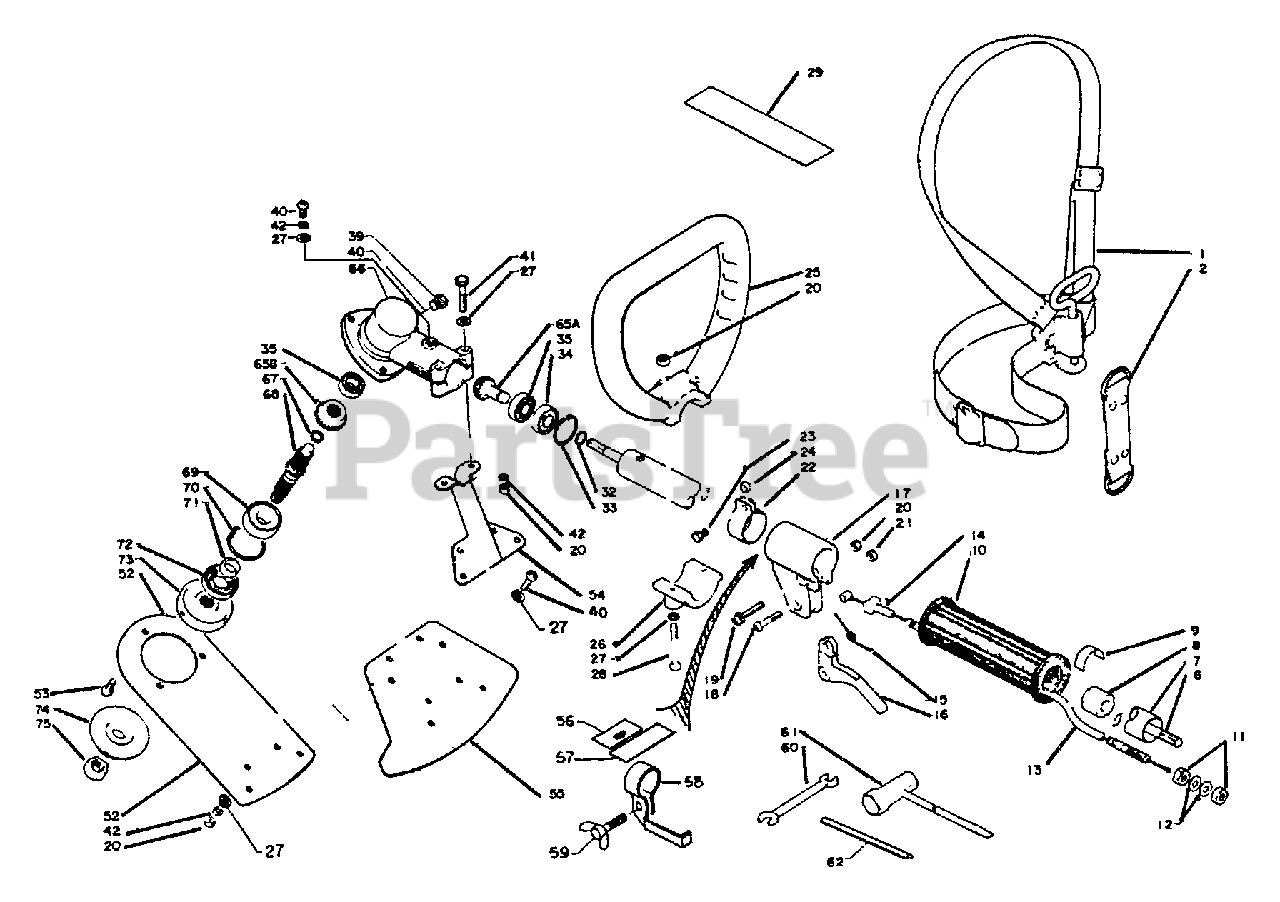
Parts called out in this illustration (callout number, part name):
1	SHOULDER STRAP ASSY
2	STRAP
6	DRIVESHAFT
7	MAIN PIPE ASSY
8	STOPPER
9	LABEL - ALIGNMENT
10	GRIP
12	WASHER - 6
13	CABLE, THROTTLE
14	GUIDE, CABLE
15	SPRING, TRIGGER
16	TRIGGER, THROTTLE
17	BRACKET, TRIGGER
18	SCREW - 5X30
19	SCREW - 5X28
21	LOCKNUT - 5
23	BOLT - 5X10
25	LOOP HANDLE ASSY
26	LOOP HANDLE ASSY
27	WASHER - 5
28	SCREW - 5X40
29	LABEL - CAUTION
32	RING, RETAINING
33	RING, RETAINING - 25
34	BEARING, BALL - 609
35	BEARING, BALL - 609
39	BOLT - 8X6
40	SCREW - 5X10
41	BOLT - 5X35
42	LOCKWASHER - 5
52	BRACKET, SHIELD
53	SCREW - 5X10
54	BRACKET, SHIELD
55	SHIELD, DEBRIS - METAL
56	LABEL
57	LABEL
58	BRACKET
59	THUMBSCREW
60	SPANNER - 8X10mm
61	T-WRENCH - 17X19mm
62	LOCKING TOOL
65	GEAR SET
65A	GEAR SET
65B	GEAR SET
66	CASE, GEAR
67	RING, RETAINING - 12
68	GEAR - SHAFT
69	BEARING, BALL - 6201
70	RING, RETAINING - 32
72	SEAL, OIL
73	ADAPTOR, BLADE - UPPER
74	ADAPTOR, BLADE - LOWER
75	NUT - 10 -- LEFT HAND
